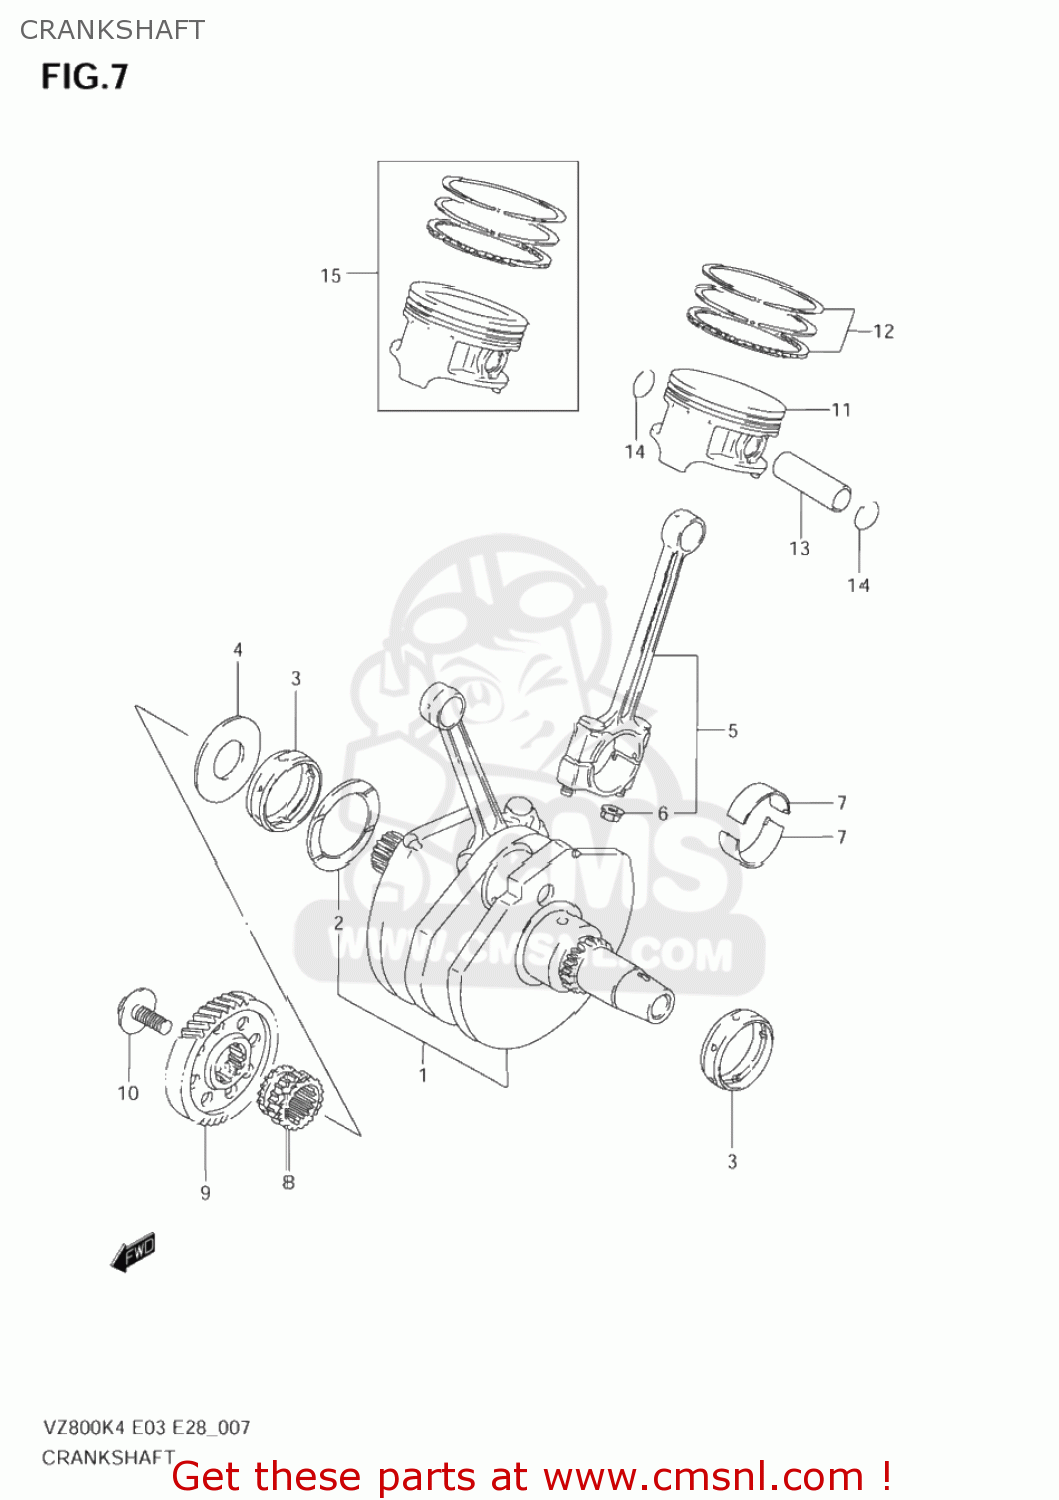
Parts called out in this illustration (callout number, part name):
1	CRANKSHAFT SET
2	WASHER(48.1X64X1.94)
3	METAL,CRANKSHAFT
4	WASHER,CRANK THRUST
5	CONNECTING ROD ASSY
6	NUT
7	BEARING,CRANK PIN
8	SPROCKET,CAM CHAIN DRIVE,R
9	GEAR,PRIMARY DRIVE
10	BOLT(12X28)
11	PISTON
12	RING SET,PISTON
13	PIN,PISTON
14	CIRCLIP,PISTON PIN
15	PISTON SET(OS:0.5)
